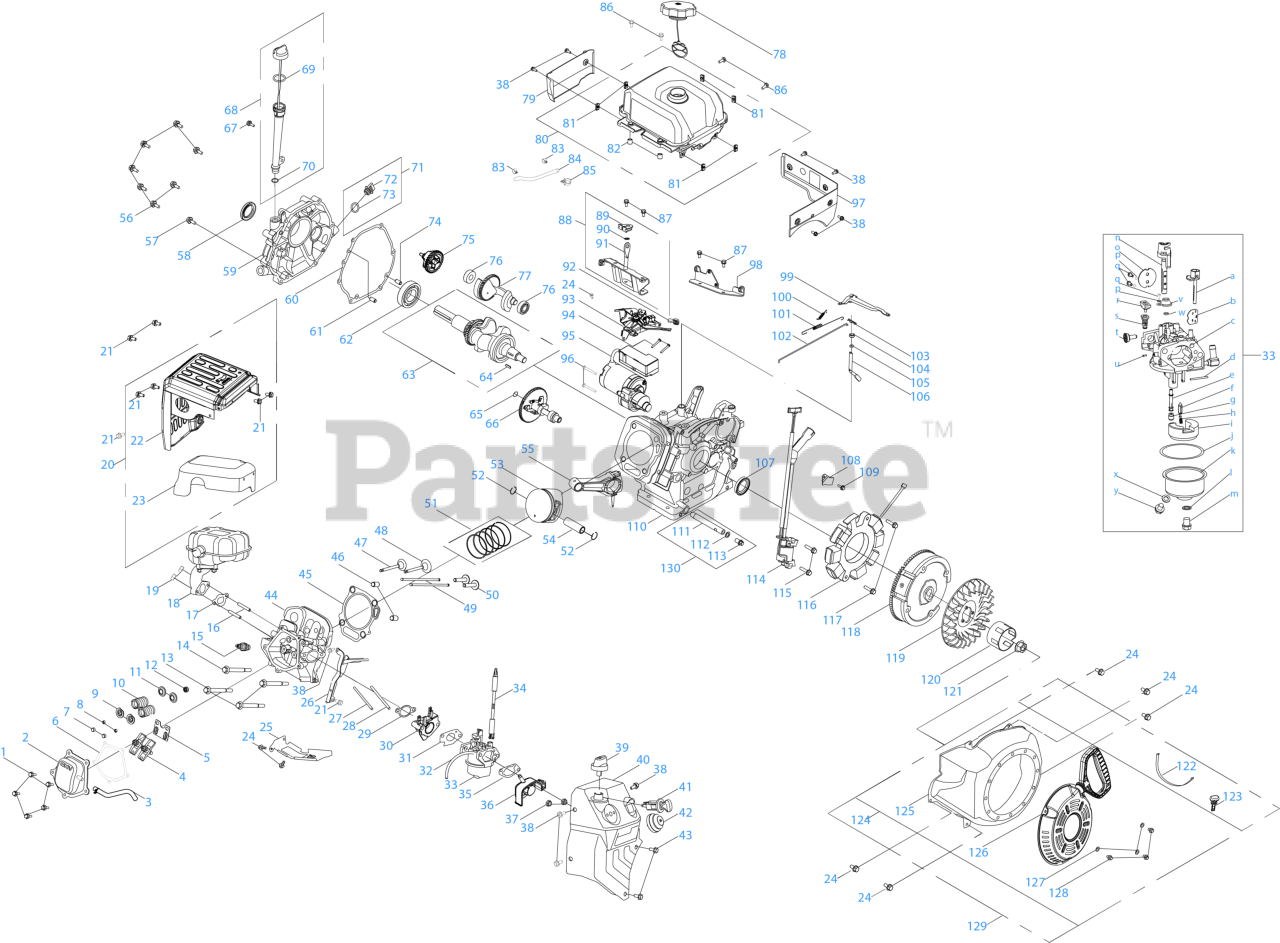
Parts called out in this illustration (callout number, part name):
1	BOLT M6 x 16
2	VALVE COVER
3	BREATHER HOSE
4	ROCKER ARM ASSEMBLY
5	PUSH ROD GUIDE
6	VALVE COVER GASKET
7	EXHAUST VALVE ADJUSTER
8	VALVE CAP
9	VALVE SPRING SEAT
10	VALVE SPRING
11	VALVE SPRING RETAINER
12	INTAKE VALVE SEAL
13	SCREW M10-1.25 x 87 x GR10.9
14	SCREW M10-1.25 x 65 x GR10.9
15	SPARK PLUG
16	STUDS M8-1.25 x 48.5
17	MUFFLER GASKET
18	MUFFLER
19	NUT M8
20	MUFFLER SHIELD ASSEMBLY
21	BOLT M6-1 x 10 GR8.8
22	MUFFLER SHIELD (OUTER)
23	INNER MUFFLER SHIELD
24	BOLT M6-1 x 12 GR8.8
25	CYLINDER BAFFLE
26	RECOIL SNOW GUARD
27	STUD M6 x 123
28	STUD M6-1 x 104
29	CARBURETOR INSULATOR GASKET
30	INSULATOR
31	CARBURETOR INSULATOR GASKET
32	PRIMER HOSE
33	CARBURETOR
34	CHOKE KNOB SHAFT
35	HEATER BOX CARBURETOR GASKET
36	HEATER BOX
37	HEX NUT
38	BOLT M6-1 x 14 GR8.8
39	CHOKE LEVER
40	CONTROL PANEL
41	ENGINE KEY SWITCH ASSEMBLY
43	SCREW M6-1 x 20 CL5.8
44	CYLINDER HEAD (690-WU) ZS
45	CYLINDER HEAD GASKET
46	DOWEL PIN
47	EXHAUST VALVE
48	INTAKE VALVE
49	PUSH ROD
50	TAPPET
51	PISTON RING SET
52	PISTON PIN SNAP RING
53	PISTON
54	PISTON PIN
55	CONNECTING ROD ASSEMBLY
56	SCREW M8-1.25 x 38 GR10.9
57	BOLT M8 x 45
58	OIL SEAL
59	CRANKCASE COVER
60	CRANKCASE COVER GASKET
61	DOWEL PIN
62	BALL BEARING
63	CRANKSHAFT ASSEMBLY
64	FLYWHEEL KEY
65	WASHER
66	ENGINE CAMSHAFT ASSEMBLY
67	BOLT M6-1 x 18 GR8.8
68	OIL DIPSTICK ASSEMBLY
69	DIPSTICK O-RING
70	O-RING
71	OIL DRAIN PLUG ASSEMBLY
72	OIL PLUG
73	O-RING
74	DOWEL PIN
75	GOVERNOR GEAR/SHAFT ASSEMBLY
76	BALL BEARING
77	BALANCE GEAR ASSEMBLY
78	FUEL CAP
79	FUEL TANK BACK PANEL
80	FUEL TANK ASSEMBLY
81	THREADED TAB
82	BUSHING
83	HOSE CLAMP
84	FUEL HOSE
85	FUEL LINE SUPPORT CLAMP
87	BOLT M8-1.25 x 14 GR8.8
88	FUEL TANK MOUNTING BRACKET
89	RUBBER GROMMET
90	RUBBER GROMMET
91	FUEL TANK MOUNTING BRACKET
92	THROTTLE CONTROL KNOB
93	THROTTLE CONTROL ASSEMBLY
95	ELECTRIC STARTER
96	BOLT M8-1.25 x 55 GR8.8
97	FUEL TANK FRONT PANEL
98	FUEL TANK BASE BRACKET
99	GOVERNOR ARM ASSEMBLY
100	GOVERNOR SPRING
101	IDLE SPRING
102	GOVERNOR ROD
103	GOVERNOR SHAFT CLIP
104	GOVERNOR SEAL
105	FLAT WASHER
106	GOVERNOR SHAFT
107	OIL SEAL
108	ALTERNATOR WIRE CLAMP BRACKET
109	BOLT M6-1 x 8 GR8.8
110	CRANKCASE COMPLETE
111	OIL DRAIN PIPE
112	WASHER
113	OIL DRAIN PLUG
114	IGNITION MODULE
115	IGNITION COIL BOLT M6-1 x 28 GR8.8
116	ALTERNATOR
117	BOLT-M6-1 x 30 GR8.8
118	FLYWHEEL
119	COOLING FAN
120	STARTER CUP
121	FLYWHEEL NUT M16X1.5
122	CABLE TIE - 3 x 150
123	IGNITION KEY
124	BLOWER HOUSING ASSEMBLY
125	BLOWER HOUSING
126	RECOIL ASSEMBLY
127	RECOIL FLAT WASHER
128	BOLT M6 x 10
129	RECOIL STARTER
130	OIL DRAIN PIPE
